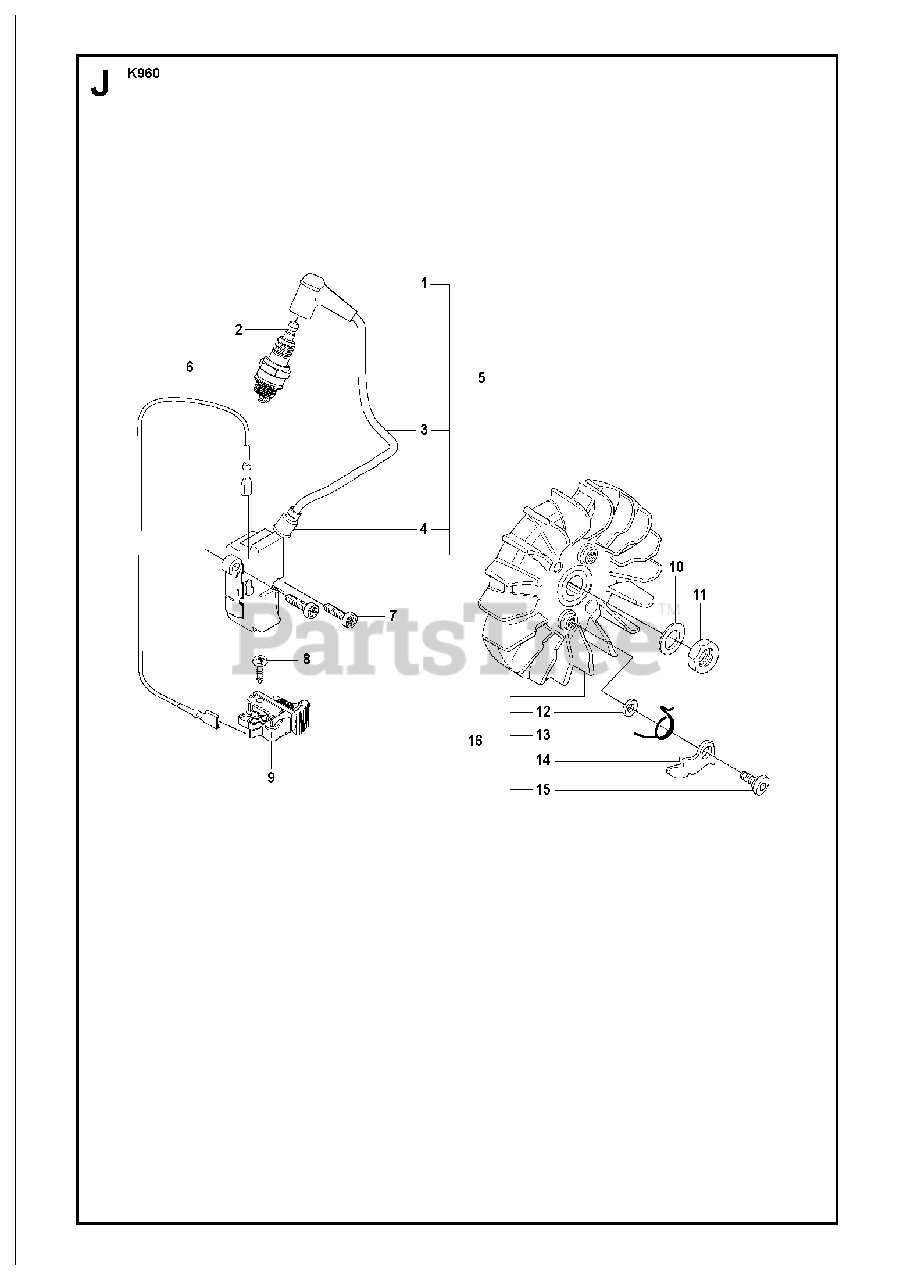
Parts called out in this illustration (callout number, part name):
1	SPARK PLUG CAP
3	IGNITION CABLE
5	IGNITION MODULEIncl. 1, 3, 4
7	SCREW ITXSCM
8	SCREW CCRPANT
9	STOP SWITCH
16	FLYWHEELIncl. 12 - 15
